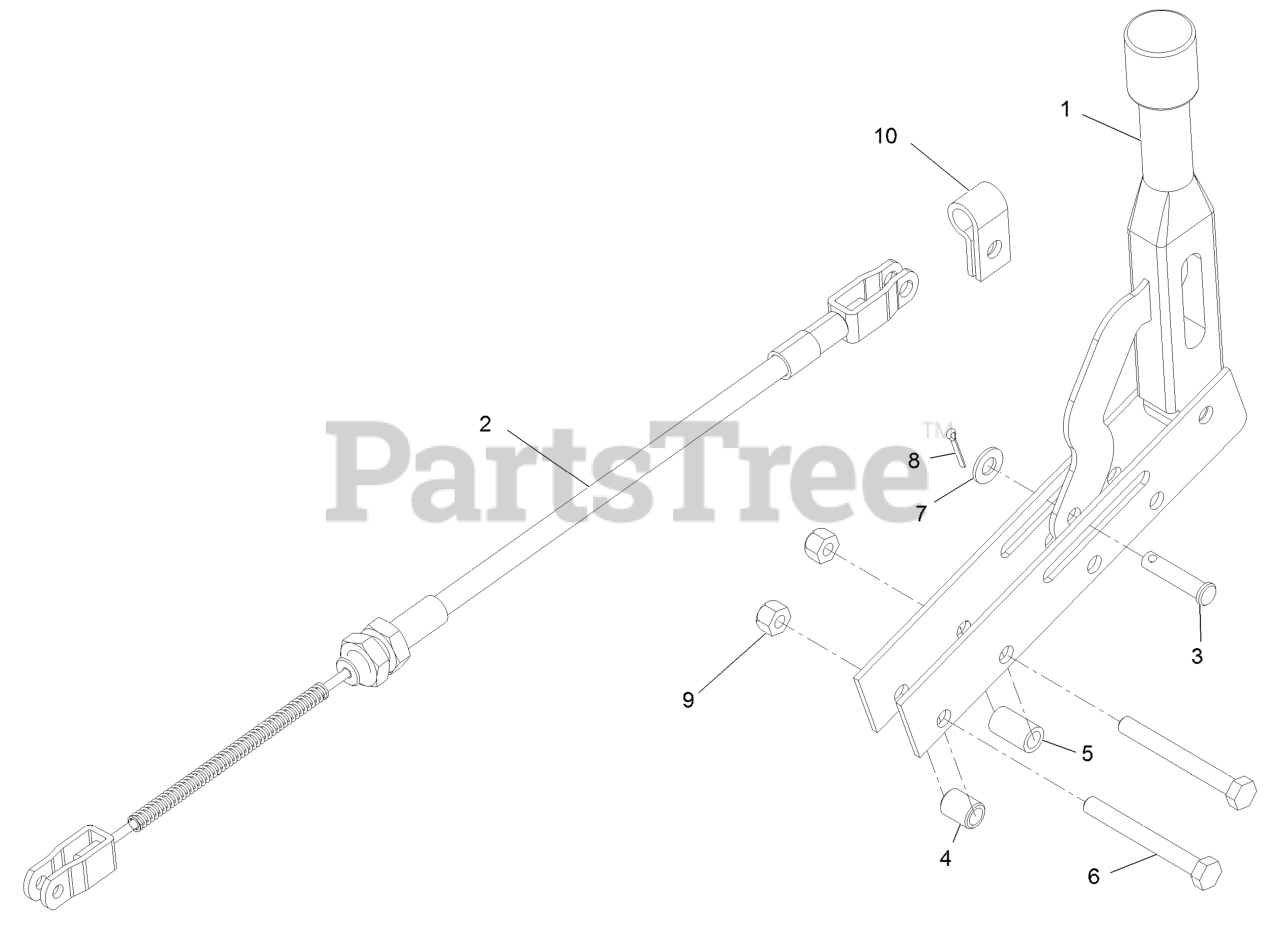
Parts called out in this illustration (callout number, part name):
1	LEVER-BRAKE
2	CABLE-BRAKE
3	PIN-CLEVIS
4	SPACER-LEVER, CONTROL
5	SPACER-IDLER
6	SCREW-HH
7	WASHER-PLAIN
8	PIN-COTTER
9	NUT-LOCK, NI
10	Clamp-Conduit
